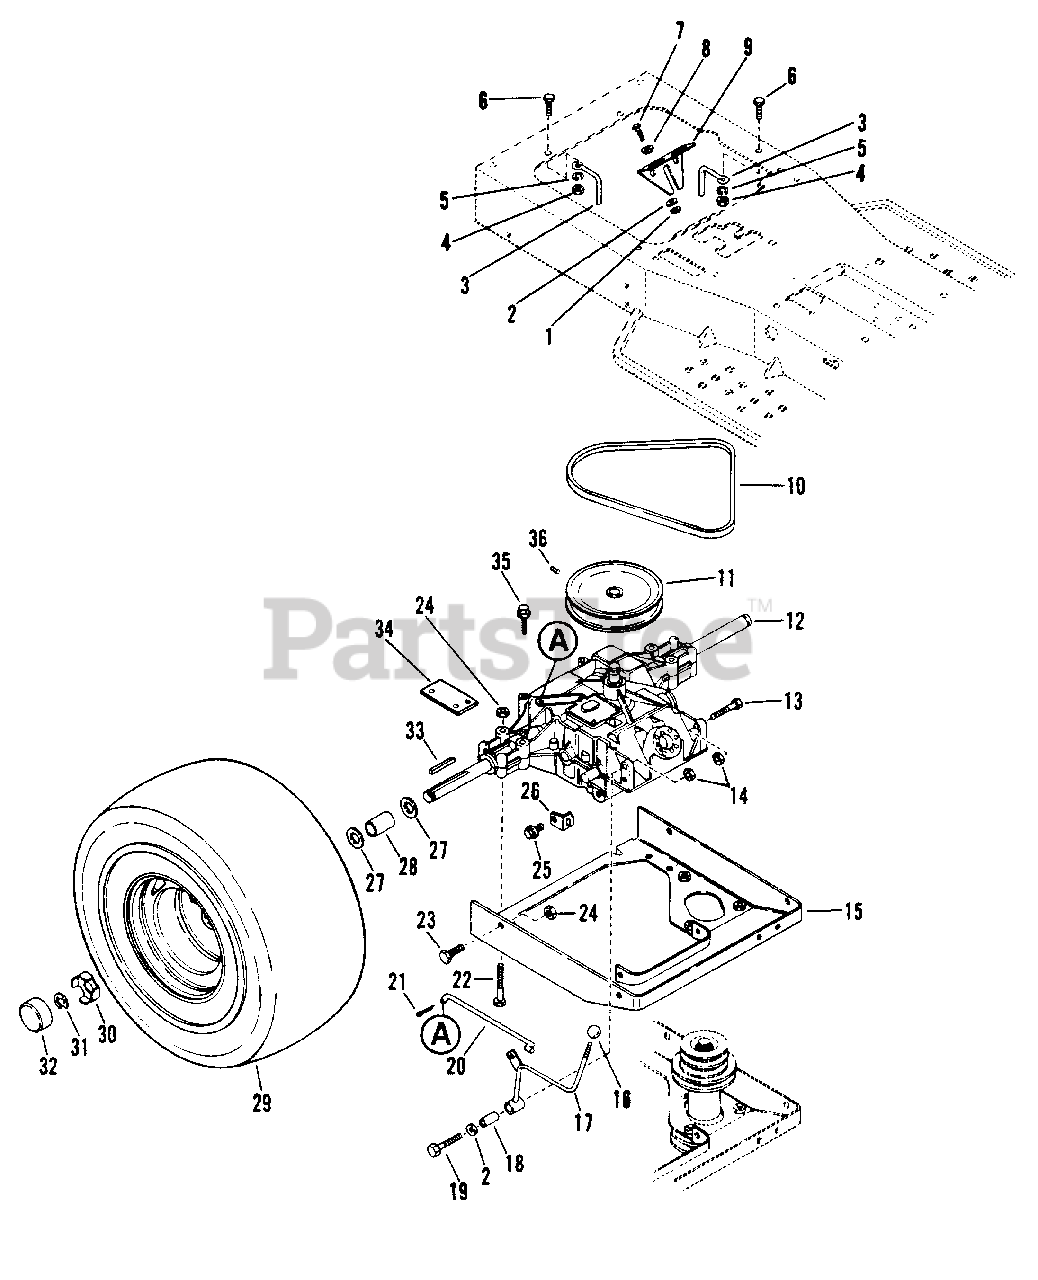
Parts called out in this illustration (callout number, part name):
1	NUT, LOCK 5/16-18
2	WASHER, FLAT .312X.734X.065
3	FINGER, BELT
4	NUT, HEX 3/8-16
5	WASHER, LOCK 3/8 REG.
6	BOLT, HEX 3/8-16X1.25
7	BOLT, HEX 5/16-18X.875
8	SPACER
9	ACTUATOR, CAM
10	BELT, TRACTION
11	SHEAVE, TRANSAXLE
12	ASSEMBLY, TRANSMISSION COMPLETE
13	BOLT, HEX 1/4-20X1.00
14	NUT, LOCK 1/4-20
15	MOUNT, TRANSMISSION
16	KNOB, ADJUSTMENT CONTROL
17	LEVER, RANGE SELECTOR
18	SPACER
19	BOLT, HEX 1/4-20X2.00
20	ROD, SELECTOR
21	PIN, COTTER .094X.75
22	BOLT, HEX 3/8-16X2.75
23	BOLT, HEX 3/8-16X1.00
24	NUT, LOCK 3/8-16
25	BOLT, HEX 5/16-18X.50
26	ANCHOR, SPRING
27	WASHER, FLAT .813X1.37X.100
28	SPACER
29	ASSEMBLY, TIRE AND WHEEL
30	CUP, SPINDLE
31	E-RING
32	CAP, HUB
33	KEY, STRAIGHT .187X2.00X.187
34	PLATE, ANCHOR
35	SCREW, TAPTITE
36	SCREW, SET 1/4-20X.375 HSCP
